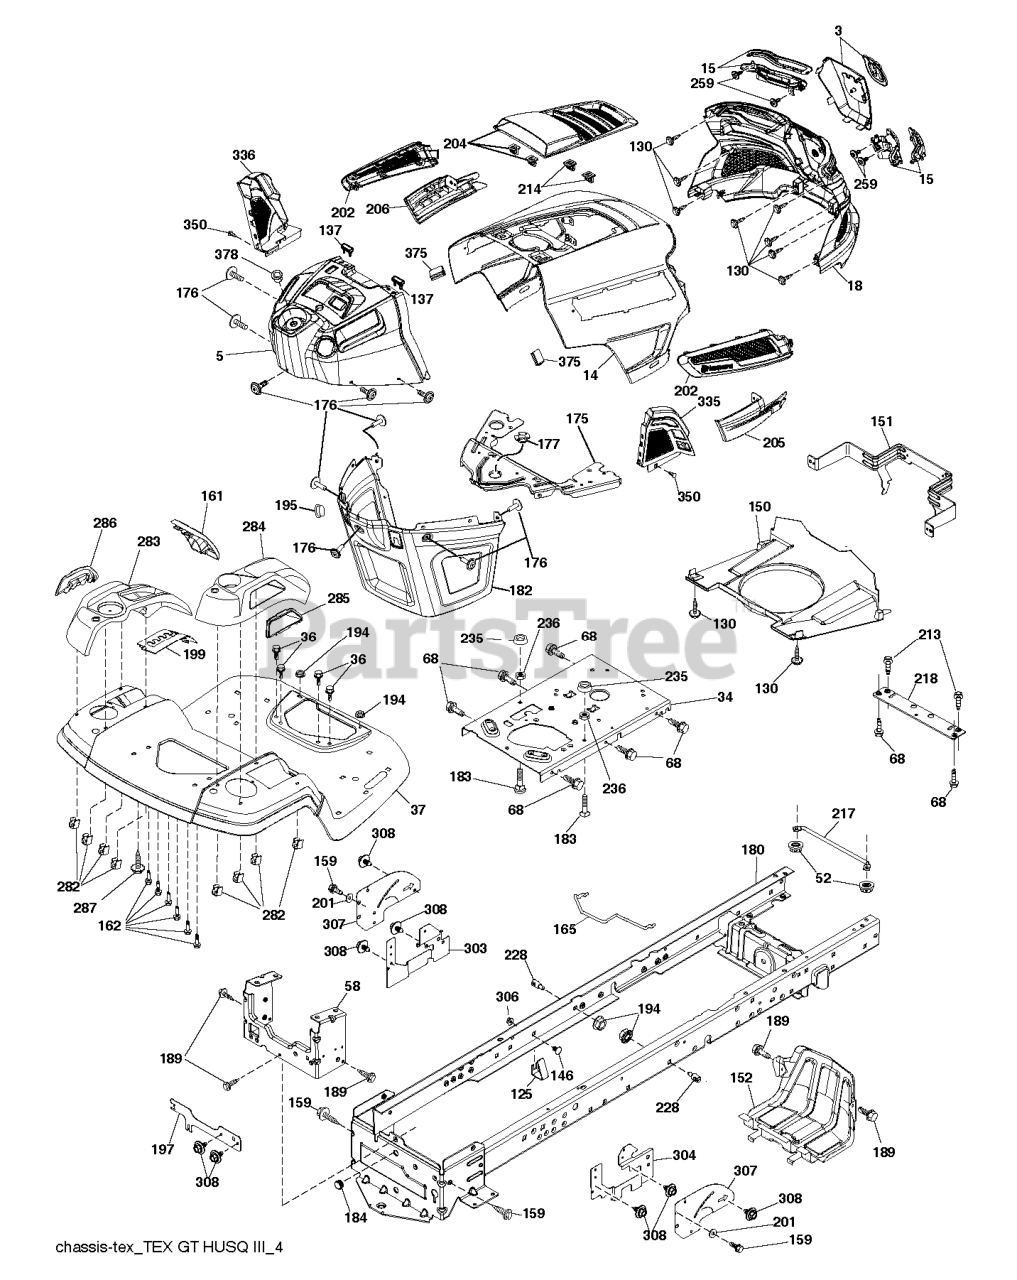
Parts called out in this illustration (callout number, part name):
5	DASHBOARD.UPPER.ASM.GT2.498
14	HOOD.ASM.HUSQVARNA.GT.TEX.ORAN
15	Service Kit
34	PLATE.ENGINE.WELDED.CHASSIS
36	SCREW 5/16"
37	FENDER.TLT.FS.W/CPH/FW/RSF.668
58	DRAWBAR UPPER 2PC SMALL FENDER
125	CLIP.FUEL.LINE
137	BUMPER DASH
146	BOLT.RDHD.SHT.SQNK.3/8-16X5/8
150	AIR.DUCT.GTV.BLACK
151	BRACKET.PIVOT.HOOD.GT.HUSQ.II
152	SHIELD.BROWNING.PNT.GT.V2
159	SCREW, 3/8-16X3/4
161	WINDOW.FUEL.LT.HUSQ.TEX.498
165	SUPPORT.TANK.REAR.W/TEX
175	PLATE.PNT.CROSSMEMBER.HUSQ/PRE
176	SCREW.#10-24X5/8.RN.QU
177	BUSHING STEERING
180	CHASS.WLDMNT.TLT.12GA/2PC.20"
182	DASH LOWER.HUSQ.PRED NO CRUISE
184	PLUG.DEMO.625
189	SCREW
195	PLUG.HOLE.DASH.LOWER.12V.BLK
197	SHIELD.DRAWBAR.LT.REAR.TANK
199	PLATE.DECK.LIFT.HUSQ.LT
201	WASHER
205	SIDE.TRIM.RH.GT.HUSQ.II
206	SIDE.TRIM.LH.GT.HUSQ.II.GRAY
213	SCREW HEXAGON HEAD SCREW 5/16-
214	CLIP.RETAINER.TINNER.
217	ROD.PIVOT.HOOD
218	X-PIECE.HOOD.STOP.NON/
228	STUD.W/"D"ANTI-ROTATION
236	NUT.CENTERLOCK.5/16-
282	CLIP.RETAINER.CONSOLE.LT.HUSQ
283	CONSOLE.DECK.LIFT.R.SDFL.HUSQ
284	CONCOLE.CNTRL.PDL.HUSQ.LT.498
285	CONSOLE INSERT RH
286	CONSOLE.INSRT.LH.HUSQ.LT.BLACK
287	SCREW 1/4X20
303	SHIELD.LWR.LH.LTGT.NON30
304	SHIELD.LWR.RH.LTGT.NON30.NOTCH
306	NUT LOCK FLG 3/8-16 UNC
307	SHIELD.UPPER.LT.GT.ISO
308	BOLT.5/16-18UNCX3/4 W/SEMS.BLK
335	COVER.LOWER.DASH.RH.BLACK
336	COVER-LH.LOWER.DASH.GT2.BLACK
350	CLIP.X-MAS.TREE
375	BUMPER CLIP-ON. DASH 1"
378	BUSHING FLANGE; PLASTIC
